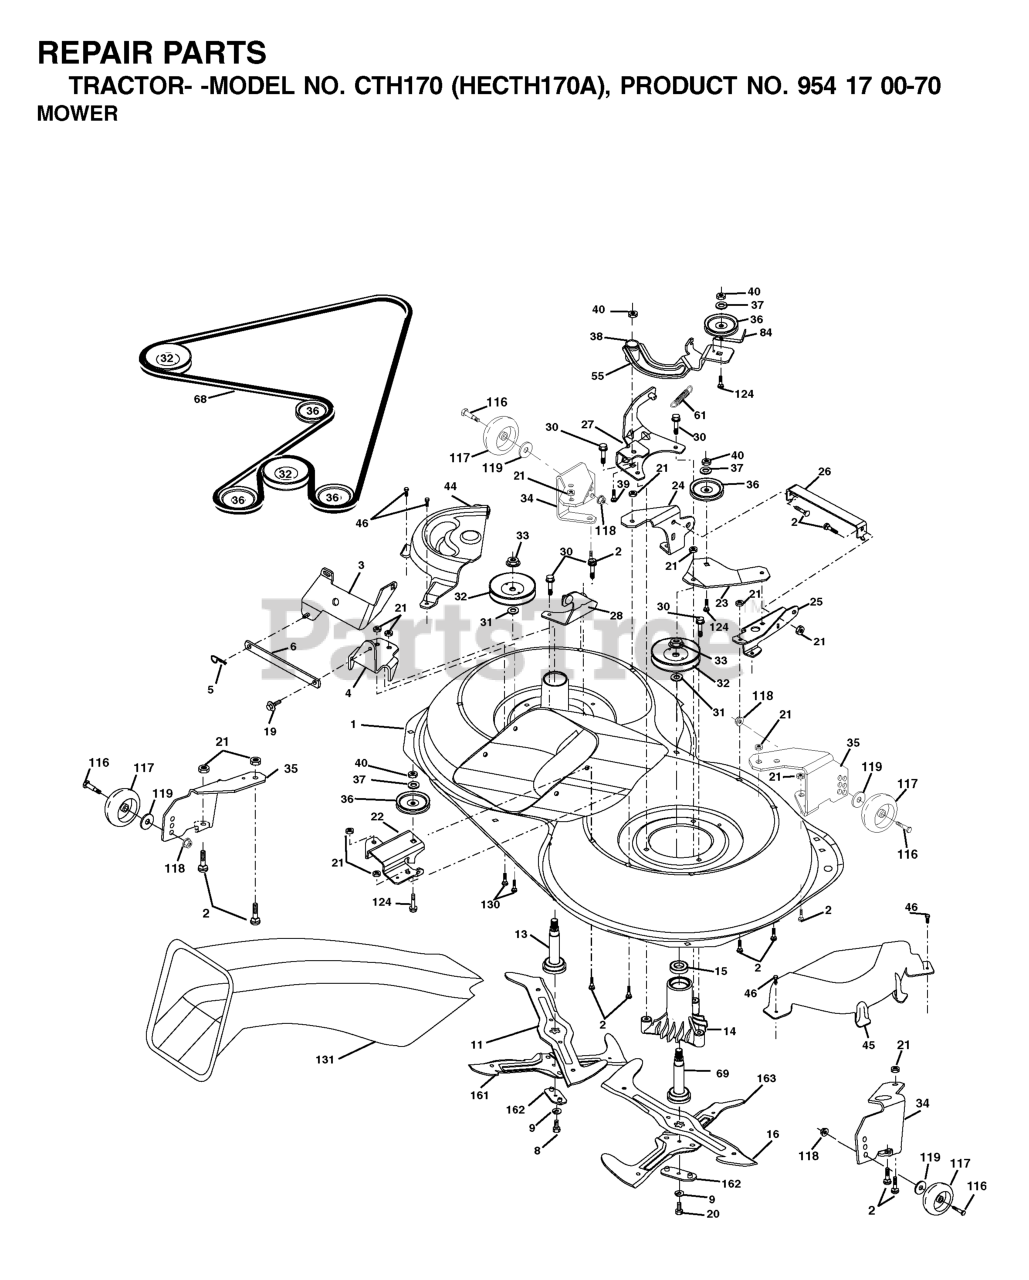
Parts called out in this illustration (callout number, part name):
1	Housing Asm. Mower 107 CRD
2	RP BOLT 5/16-18 X3/4 ZN/YEL GR
5	RETAINER-SPRNG RB
6	BAR.SWAY.92.CRD
8	BOLT.3/8-24X1.25 GR8
9	LOCKWASHER
11	BLADE.3N1.LH.CRD
13	SHAFT ASM VENT
14	HOUSING.MANDREL.VENTED (MACHD)
16	BLADE.3N1.RH.CRD
19	BOLT SHD 5/16-18
20	BOLT.3/8-24X1.25GR8. LHTHRD
21	LOCKNUT
22	BRACKET.IDLER.RR.107.CRD
25	BRACKET.SUSPENSION.RF.107.CRD
26	BRACE.SUPT.SUSP.FRT.CRD
28	BRACKET
30	SCREW, WASHER HEAD
31	WASHER
33	NUT, FLG TOPLOCK 9/16"
36	PULLEY.IDLER.4.25
37	WASHER
45	COVER.MANDREL.RH.CRD
46	SCREW.1/4-20X5/8
55	ARM.IDLER.107.CRD
68	HEX-BELT 107 MOWER
69	SHAFT.ASM.W/LWR.BRG.RH.THREAD
84	KEEPER, BELT IDLER
116	BOLT, SHOULDER
117	WHEEL GAGE DONUT
118	LOCKNUT
119	WASHER.5/16.FLAT.STE.STD.
124	BOLT.3/8-16X1.50
130	BOLT.CARR.SQNK.5/16-18UNC.X3/4
131	CHUTE BAGGER
163	BLADE.CROSS.RH.CRD.107
